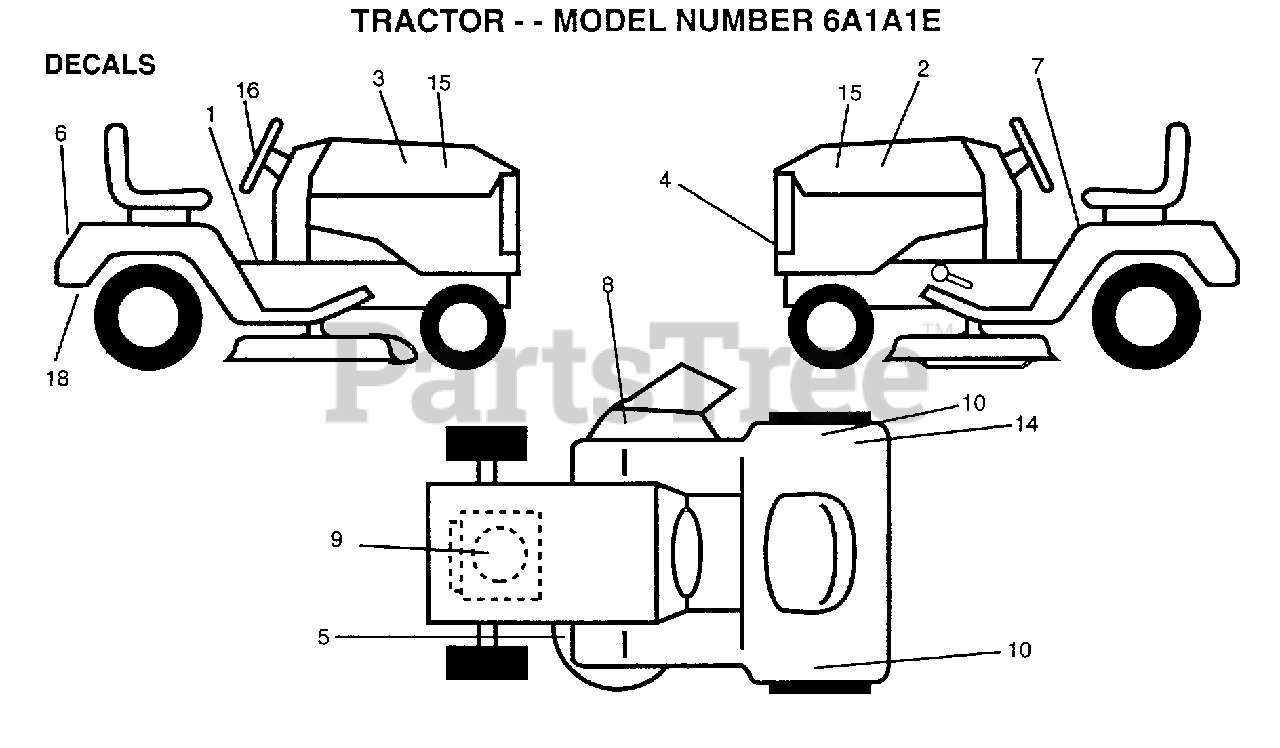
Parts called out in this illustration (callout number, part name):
1	DECAL.OP.INST.SYM
2	DECAL HD RLY LH
3	DECAL HD RLY RH
4	GRILL DECAL
5	DECAL.V.BELT
6	FENDER DECAL
7	DECAL.READ.O.MANU
8	DECAL.DANGER.CUTF
9	DECAL, ENGINE
10	DECAL.FEND.QUICKS
12	DECAL.BTRY.DANGER
16	"DECAL,STR WHL"
18	DECAL.EURO.ST.CE.
